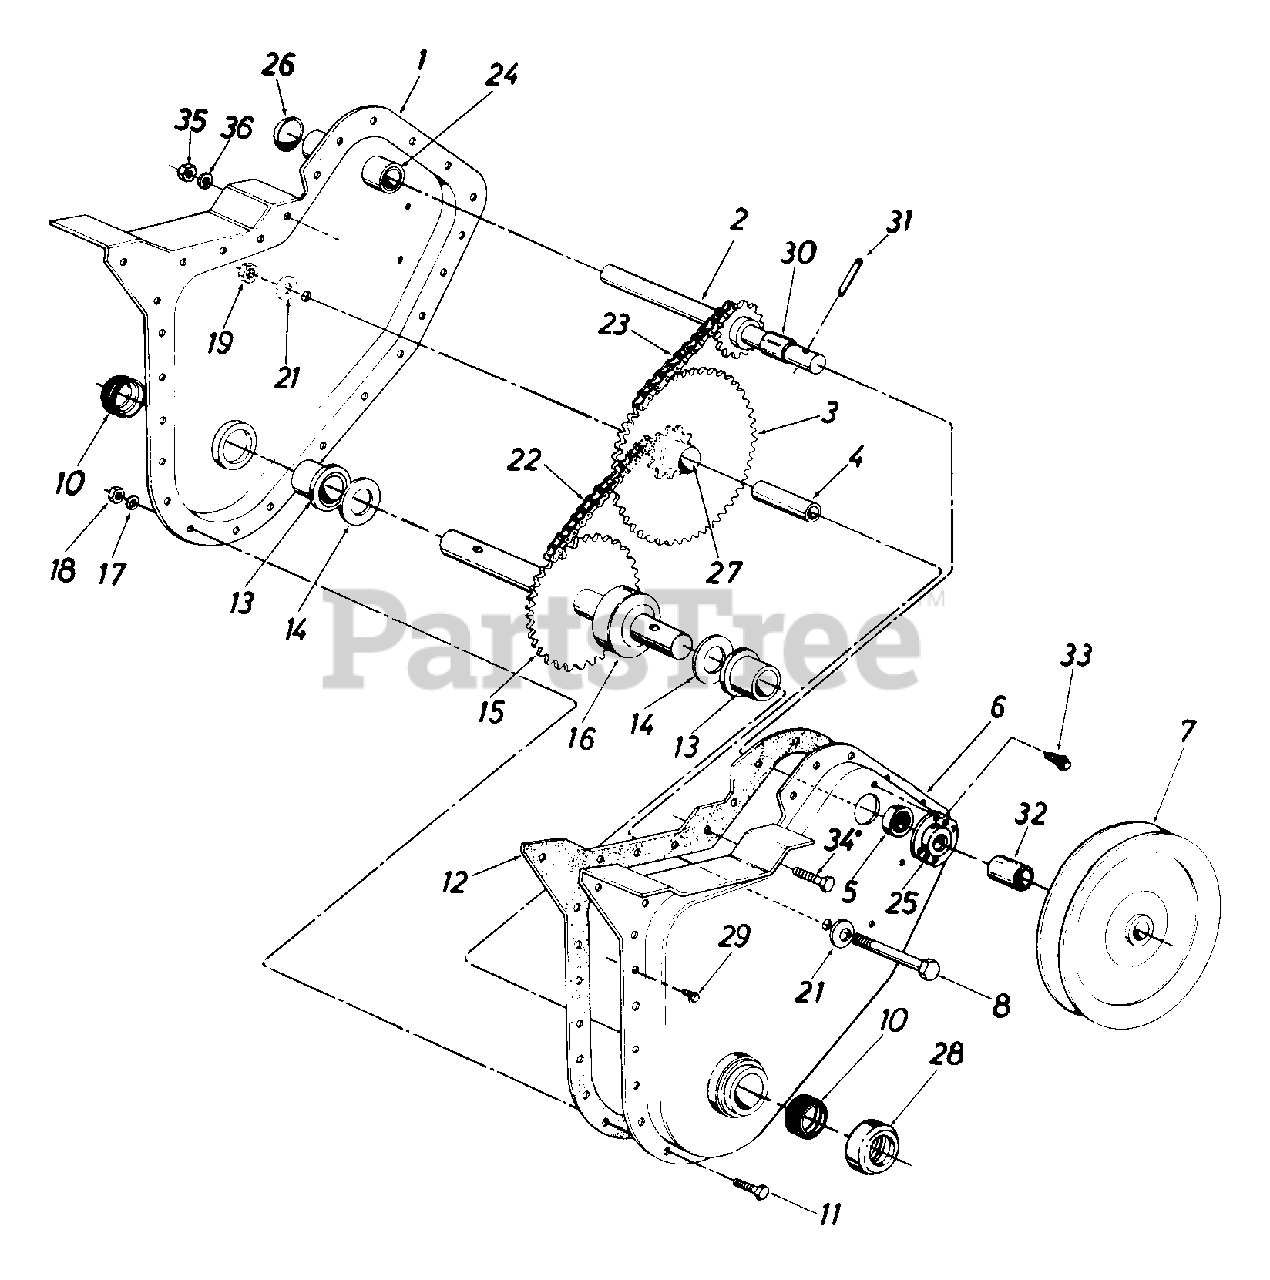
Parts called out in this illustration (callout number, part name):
1	Chain Case Ass'y. - R.H.
2	Input Shaft Ass'y.
3	Hub and Sprocket Ass'y.
4	Bearing Inner Race
5	Ball Bearing
8	Hex Bolt 3/8 - 24 x 2.5"
11	Hex Bolt 1/4 - 28 x .625"'
12	Gasket
13	Flange Brg. .879" I.D.
14	Fl-Wash. .88" I.D. x 1.5"
15	Tine Shaft Ass'y.
16	Spacer 7/8" I.D.
17	L-Wash. 1/4" I.D.
18	Hex Nut 1/4 - 28 Thd.
19	Hex Ins. L-Nut 3/8 - 24 Thd.
21	Bell-Wash. .406" I.D.
22	Chain #420 1/2" Pitch 38 Links
23	Chain #35 .375" Pitch 50 Links
24	Bearing .62" I.D. x .813"
25	Bearing Housing
26	Expansion Plug 13/16"
27	Bearing
28	Dust Cap
29	Hex Wash. Hd. Self-Tap Scr. 1/4 - 20 x .50" Lg.
30	Spacer .63" I.D. x .77" O.D. x .38" Lg.
31	Spring Pin Spiral 1/4" Dia. x 1-1/2" Lg.
32	Spacer .647 x 1.25"
33	Hex Wash. Hd. Self-Tap Scr. 1/4 - 20 x .38" Lg.
34	Hex Bolt 5/16 - 18 x .75" Lg.
35	Hex Nut 5/16 - 18 Thd.
36	L-Wash. 5/16" I.D.
